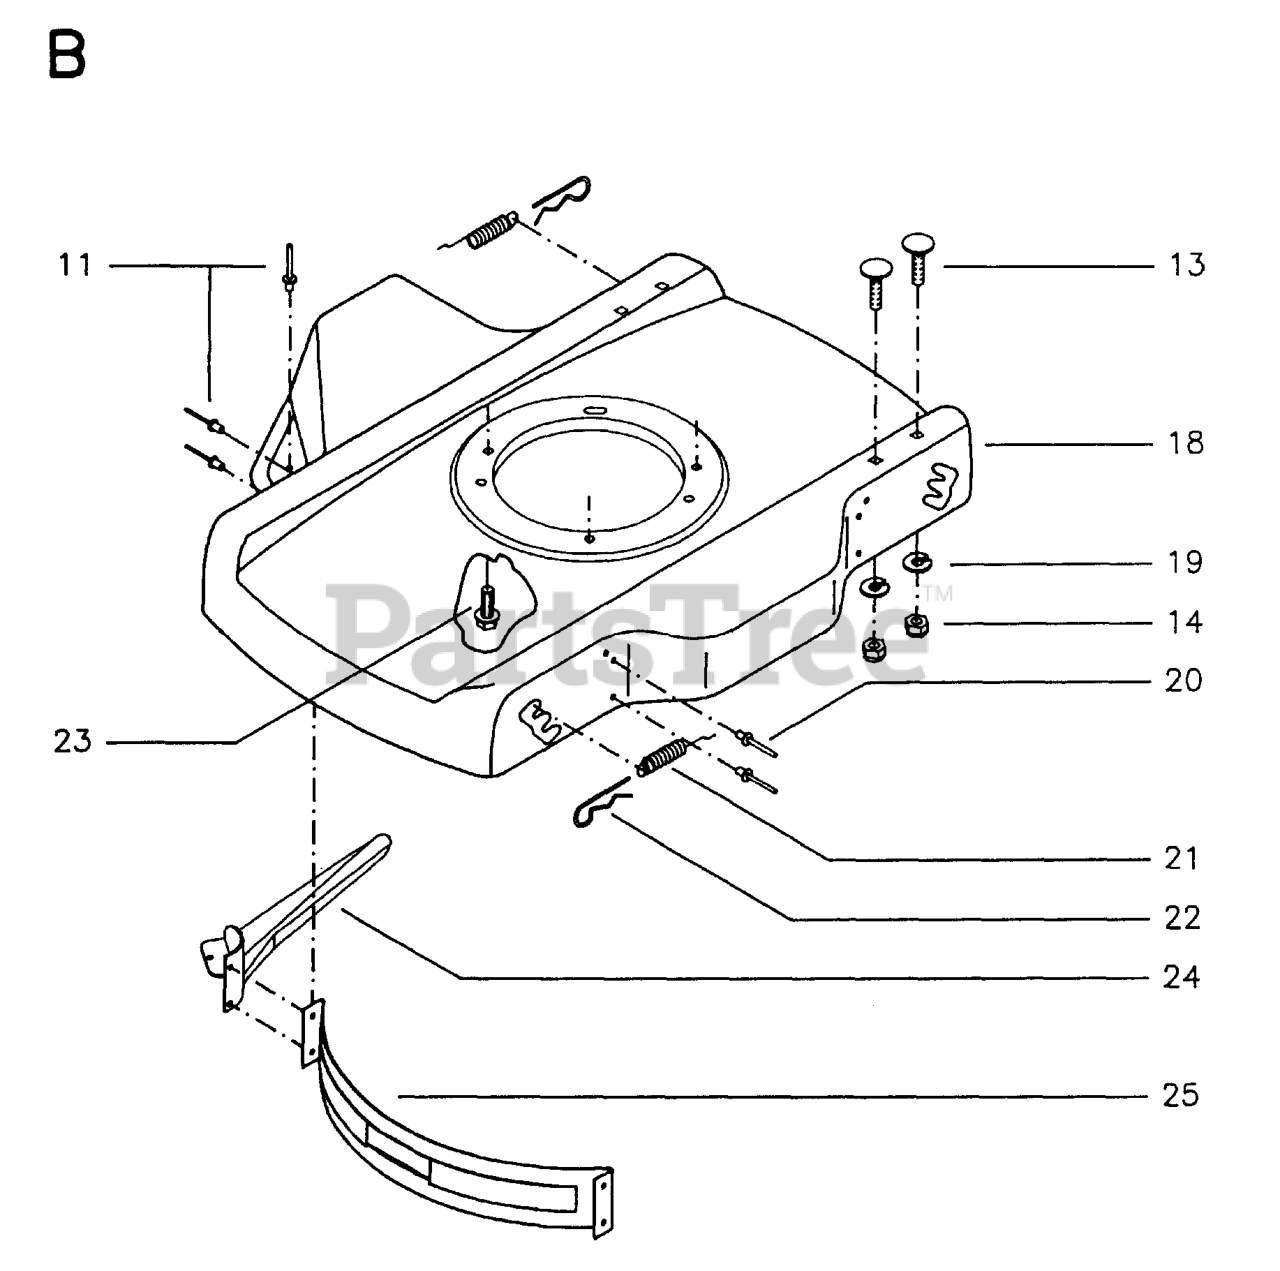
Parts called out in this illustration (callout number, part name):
11	REPL BY 516 92 38-00
14	NUT
19	SPRING WASHER
20	RIVET
